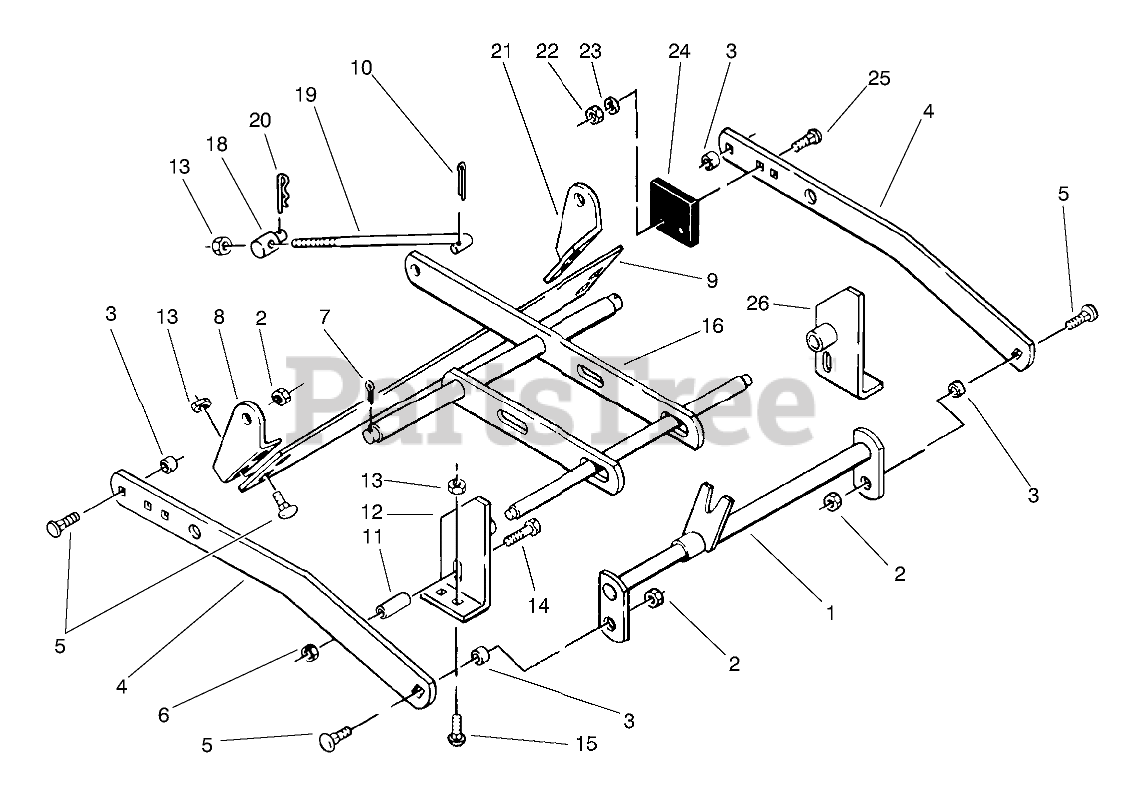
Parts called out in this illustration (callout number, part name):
1	Hitch
2	LOCKNUT-FLANGE
3	SPACER
4	Bar Draft
5	BOLT-CARR
6	NUT-LOCK, NI
7	PIN-COTTER
8	Bracket-R.H.
10	Front Shaft
11	SPACER
12	Bracket-R.H.
13	NUT-LOCK, NI
14	BOLT-CARR
15	BOLT-CARR
16	Leveler
18	TRUNNION-LIFT
19	LIFT ROD
20	PIN-HAIR
21	Bracket-L.H.
22	NUT-LOCK, NI
23	WASHER-FLAT
24	BUMPER
25	SCREW-CARR
26	Bracket-L.H.
27	PIN-COTTER
